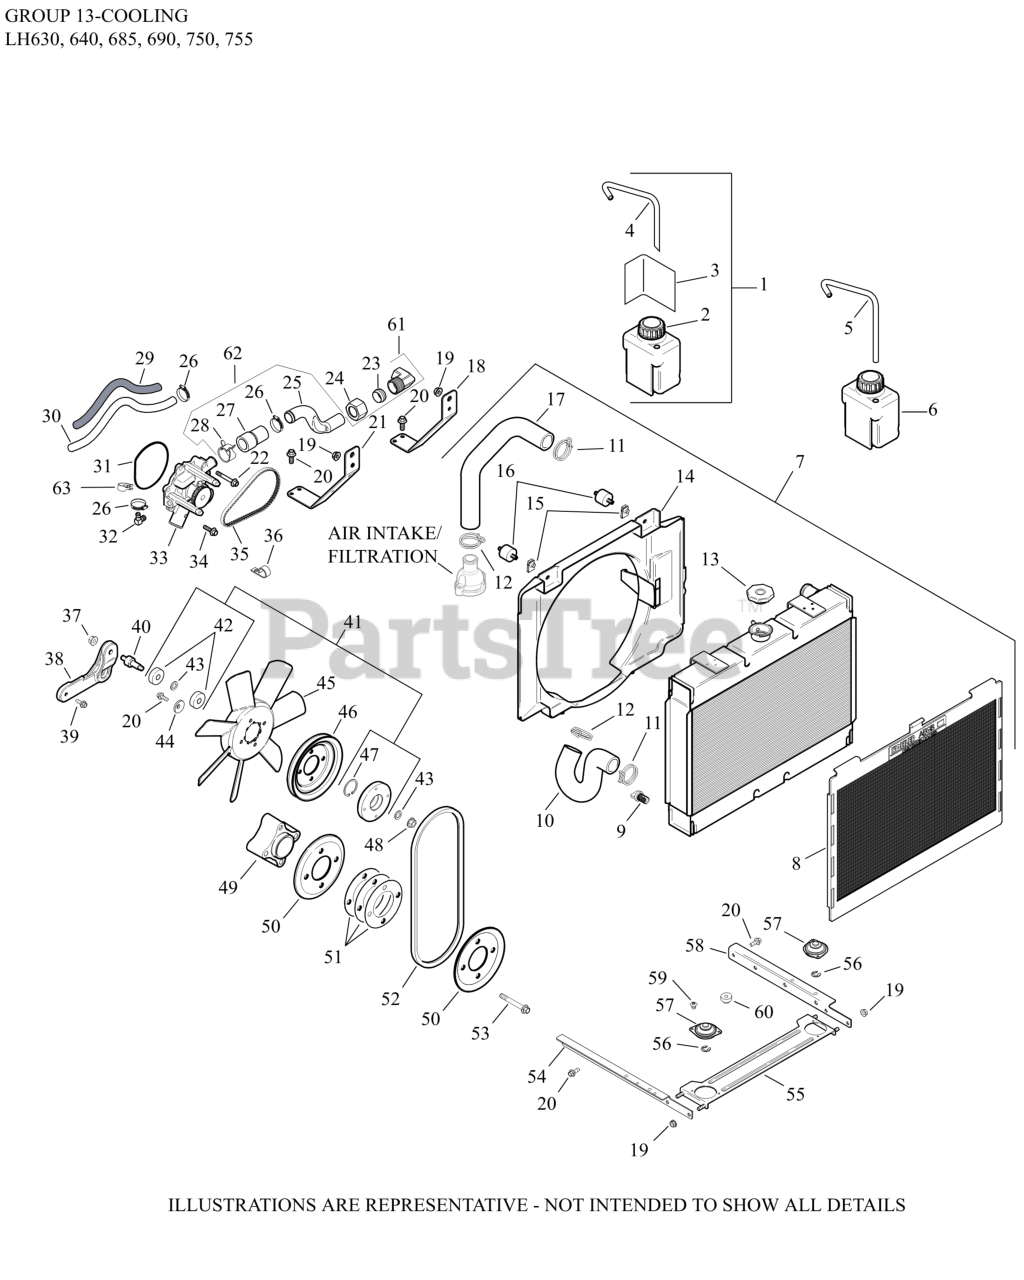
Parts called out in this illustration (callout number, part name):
1	KIT, OVERFLOW BOTTLE
2	DECAL, COOLANT LEVEL
3	CAP, OVERFLOW
4	HOSE, OVERFLOW
7	RADIATOR ASSY USE 66 398 10-S
8	SCREEN, GRASS (FLAT)-USE 66 162 12-S
9	PLUG, DRAIN
10	HOSE, RADIATOR TO WATER PUMP
11	CLAMP, CONSTANT TENSION BAND
12	CLAMP, THERMOSTAT HSG OUTLET
13	CAP, RADIATOR - (#6617309S)
15	U CLIP - DISCONTINUED
16	MOUNT, ISOLATION
17	HOSE, THERMOSTAT TO RADIATOR
18	BRACKET,UPPER RADIATOR #1 SIDE
19	NUT, FLG M6X1.0
20	SCREW, FLG M6X1.0X16
21	BRACKET,UP RADTR #2 SIDE-USE 66 126 78-S
22	SCREW, FLG M6X1.0X40
25	TUBE, CROSSOVER (METAL)
26	CLAMP, HOSE-USE 25 237 32-S
26	CLAMP, HOSE-USE 25 237 33-S
27	TUBE, CROSSOVER (RUBBER)
29	SLEEVE, INSULATING 14"
30	HOSE, BY-PASS 13"
32	CONNECTOR
33	PUMP ASSEMBLY, WATER - USE 66 393 10-S
34	SCREW, FLG M6x1.0x20
35	BELT, WATER PUMP
36	CLIP, CABLE
37	NUT, FLG M8X1.25
38	BRACKET, FAN
39	SCREW, FLG 8X1.25X16
40	KIT, FAN SHAFT
41	KIT, BEARING CARRIER
42	BEARING, BALL
44	WASHER, SPRING 1/4"
45	FAN, AXIAL PULLER
46	PULLEY, FAN
47	RING, RETAINER-INTL O.D. 30MM
49	ADAPTER, CRANKSHAFT PULLEY
50	PULLEY, CRANKSHAFT
51	SHIM, CRANKSHAFT PULLEY
52	BELT, FAN
53	SCREW, FLG M8X1.25X60
54	BRCKT KIT, LWR RADIATOR #2
55	BRACKET, RADIATOR CROSS
56	RETAINER, E-CLIP
57	MOUNT, PLATEFORM
58	BRCKT KIT, LWR RADIATOR #1
